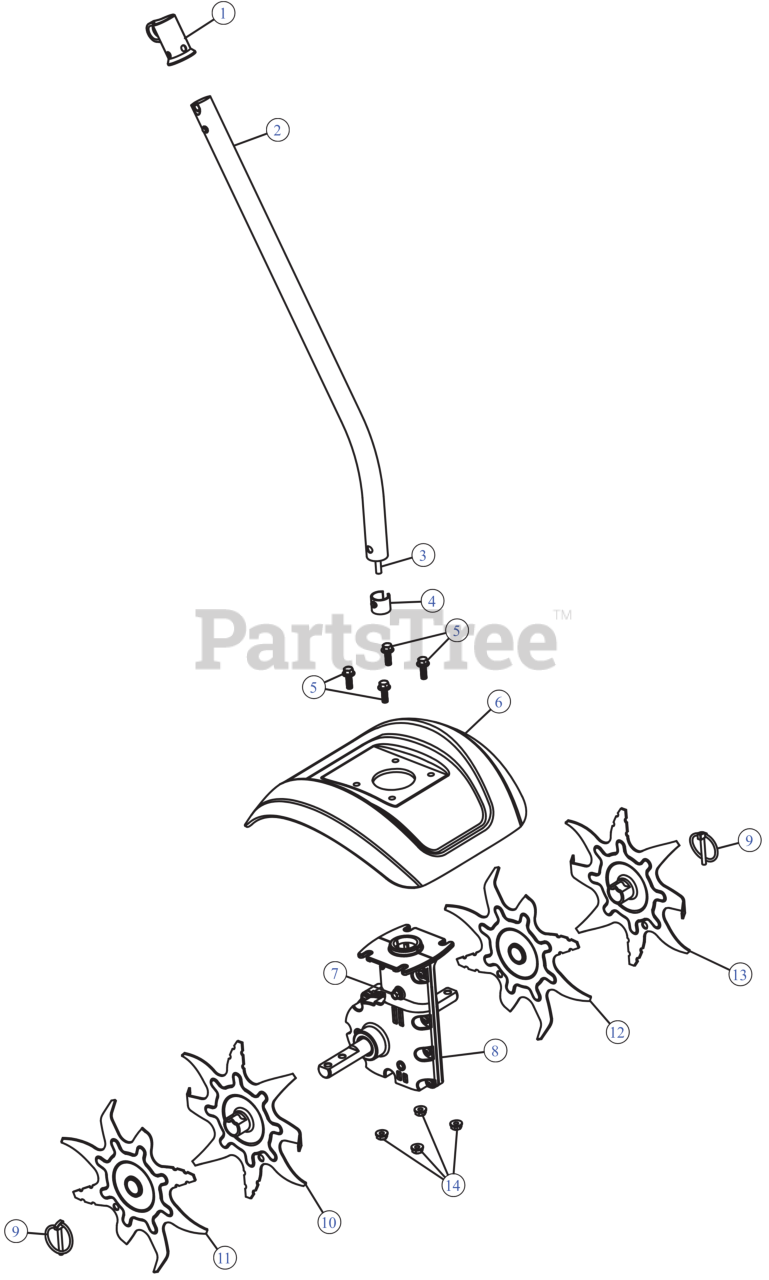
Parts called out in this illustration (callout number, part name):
2	BOOM ASSEMBLY
3	SHAFT, DRIVE
4	RETAINER SLEEVE
5	HEX SCREW 1/4-20X.
7	SCREW 1/4-20 X.500
8	GEARBOX ASSEMBLY CULT
9	LYNCH PIN .1875
10	TINE ASSEMBLY (LH)O (RH)I
11	TINE ASSEMBLY (LH)I (RH)O
12	TINE ASSEMBLY (LH)I (RH)O
13	TINE ASSEMBLY (LH)O (RH)I
14	LOCK NUT 1/4
